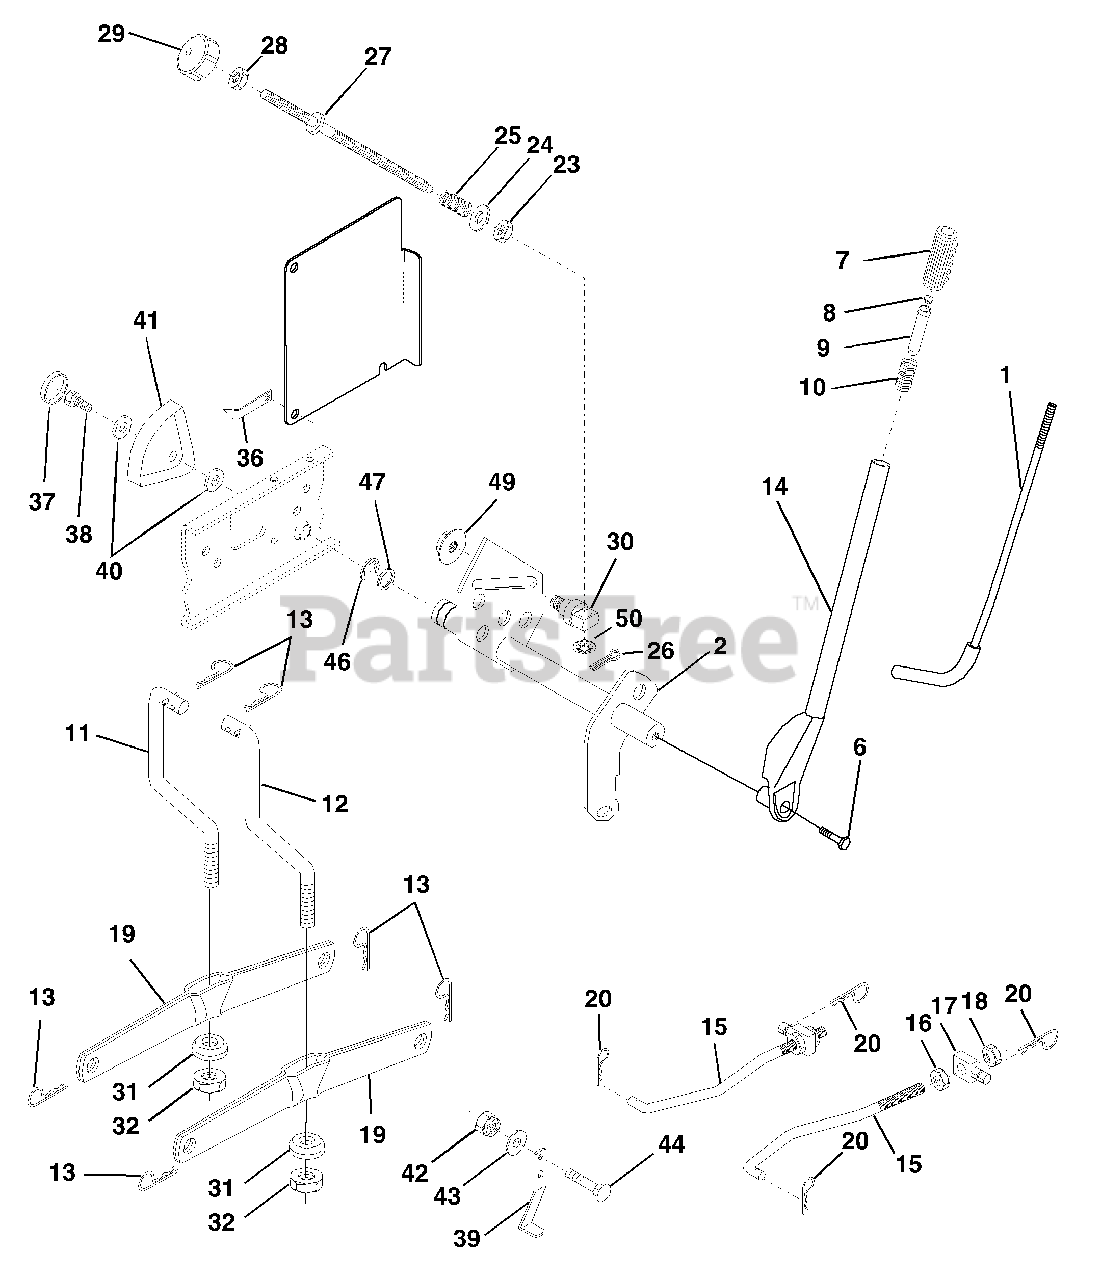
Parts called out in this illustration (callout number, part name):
1	Rod Assembly, Lever
2	Shaft Assembly, Lift
6	Bolt, Hex Head, Fin. 3/8-16 x 1-1/2
7	Grip Handle
8	Button Plunger Black
9	Plunger Lever Lift
10	Spring
11	Link, Lift, LH
12	Link, Lift, RH
13	Retainer Spring
14	Lever Assembly, Lift, RH
15	Link, Front
16	Nut, Hex, Jam 1/2-13 UNC
17	Trunnion
18	Nut Crownlock 1/2-13 Unc
19	Arm, Suspension, Rear
20	Retainer Spring
23	Nut, Special
24	Washer 13/32 x 5/8 x 16 Gauge
25	Spring
26	Pin, Cotter 3/32 x 1/2
27	Adjustment Rod, Lift
28	Nut, Hex, Jam 3/8-16 UNC
29	Knob, Infinite Height Adjustment
30	Trunnion, Inf. Height
31	Bearing
32	Nut, Crownlock 3/8-24
36	Pointer Height Indicator
37	Plug Hole Blk 1.485/1.515 Dia.
38	Screw Thdrol 5/16-18 x 3/4
39	Stop Over Center
40	Washer 11/32 x 1-1/2 10 Ga.
41	Scale Ind. Height Blk.
42	Nut, Crownlock 3/8-16 UNC
43	Washer 13/32 x 1 x 12 Ga.
44	Bolt, Carriage 3/8-16 x 1.00
49	Nut Hex Flange Lock
50	Nut Push Phos & Oil
